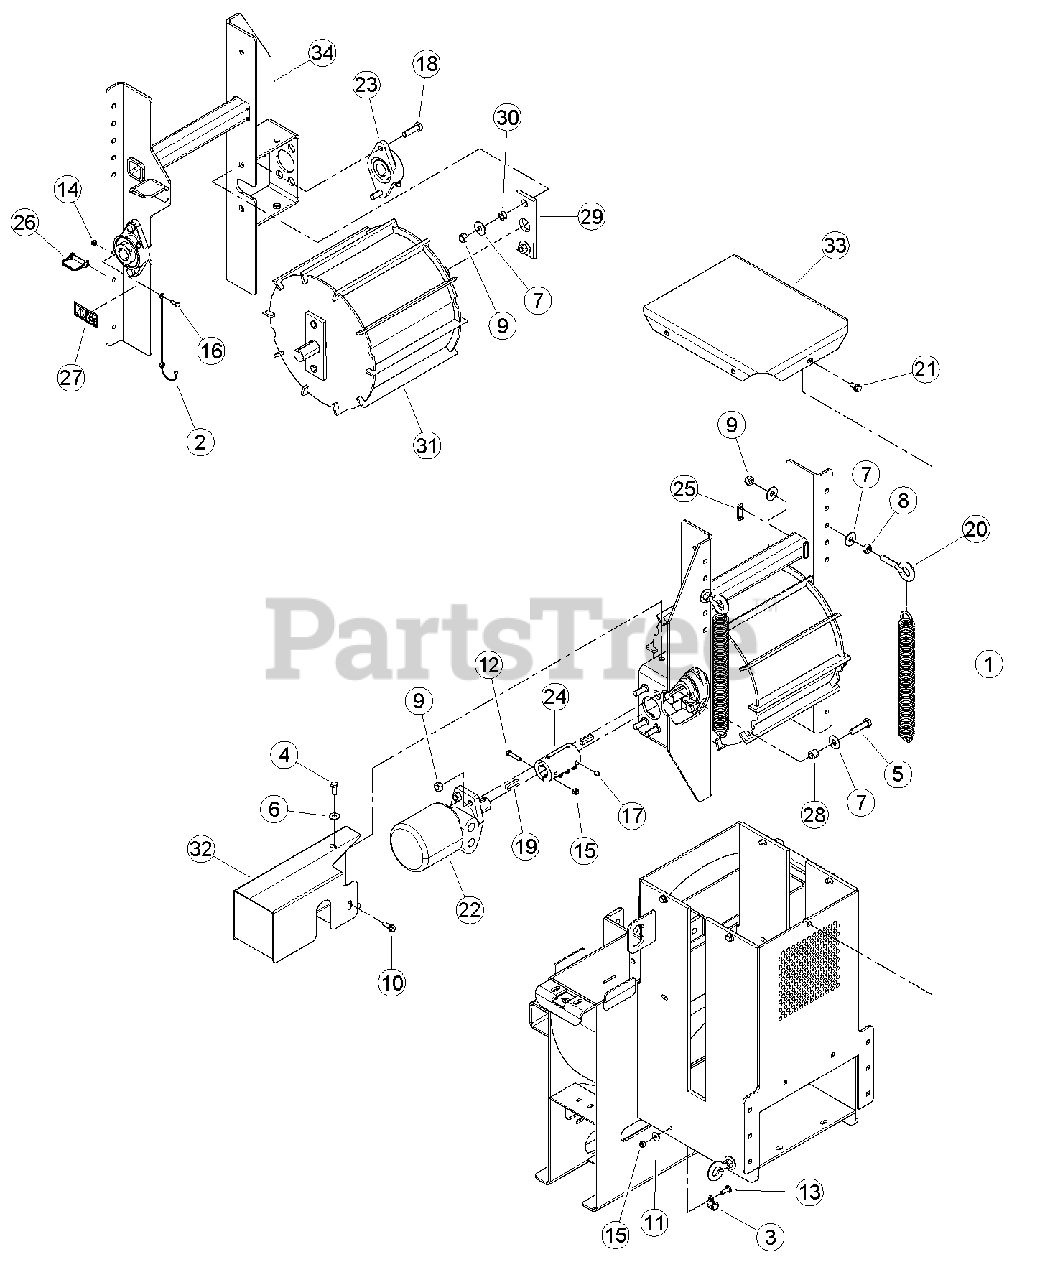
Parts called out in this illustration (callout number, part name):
1	SPRING, EXTENSION
2	LANYARD, NYLON
3	CLAMP, 9/16 COATED
4	BOLT, 3/8 X 1 HEX HD GR5 ZP
5	BOLT, 1/2 X 2 HEX HD GR5 ZP
6	WASHER, 3/8 FLAT ZP
7	WASHER, 1/2 FLAT ZP
8	NUT, 1/2 HEX NC ZP
9	NUT, 1/2 CENTERLOCK GRB ZP
10	SCREW, 3/8-16 X 1 LG THD CUTT ZP
11	WASHER, 5/16 FLAT ZP
12	BOLT, 5/16 X 1-1/2 HEX HD GR5 ZP
13	BOLT, 5/16 X 1 CRG GR5 ZP
14	NUT, 1/4 NE NYLOCK ZP
15	NUT, 5/16 NE NYLOCK ZP
16	BOLT, 1/4 X 3/4 GR5 HEX HD NF ZP
17	SET SCREW, 3/8 X 1/2 CUP PT SKT
18	BOLT, 1/2 X 1-3/4 HEX HD GR5 NC ZP
19	KEY, 5/16 SQUARE X 1-1/2 LONG
20	EYEBOLT, 1/2 X 2 ZP
21	BOLT, 3/8 X 3/4 SERR FLANGE
22	MOTOR, 45 CU IN. HYDRAULIC
23	BEARING, 1-1/4" DIA 2 BOLT FLANGE
24	COUPLER, 1-1/4" SHAFT
25	WEAR PAD, STD. SPRING HD FRONT
26	PIN, SNAP 3/8 X 1-1/2 USABLE LGH
27	DECAL, CRUSHING ISO
28	SPACER, 0.75 X 0.620
29	BEARING, SLIDE
30	SPACER, .75 OD X .5 ID X .37
31	WELDMENT, FEED ROLLER
32	WELDMENT, MOTOR COVER
33	WELDMENT, TOP ROLLER COVER
34	WELDMENT, ROLLER SLIDE
